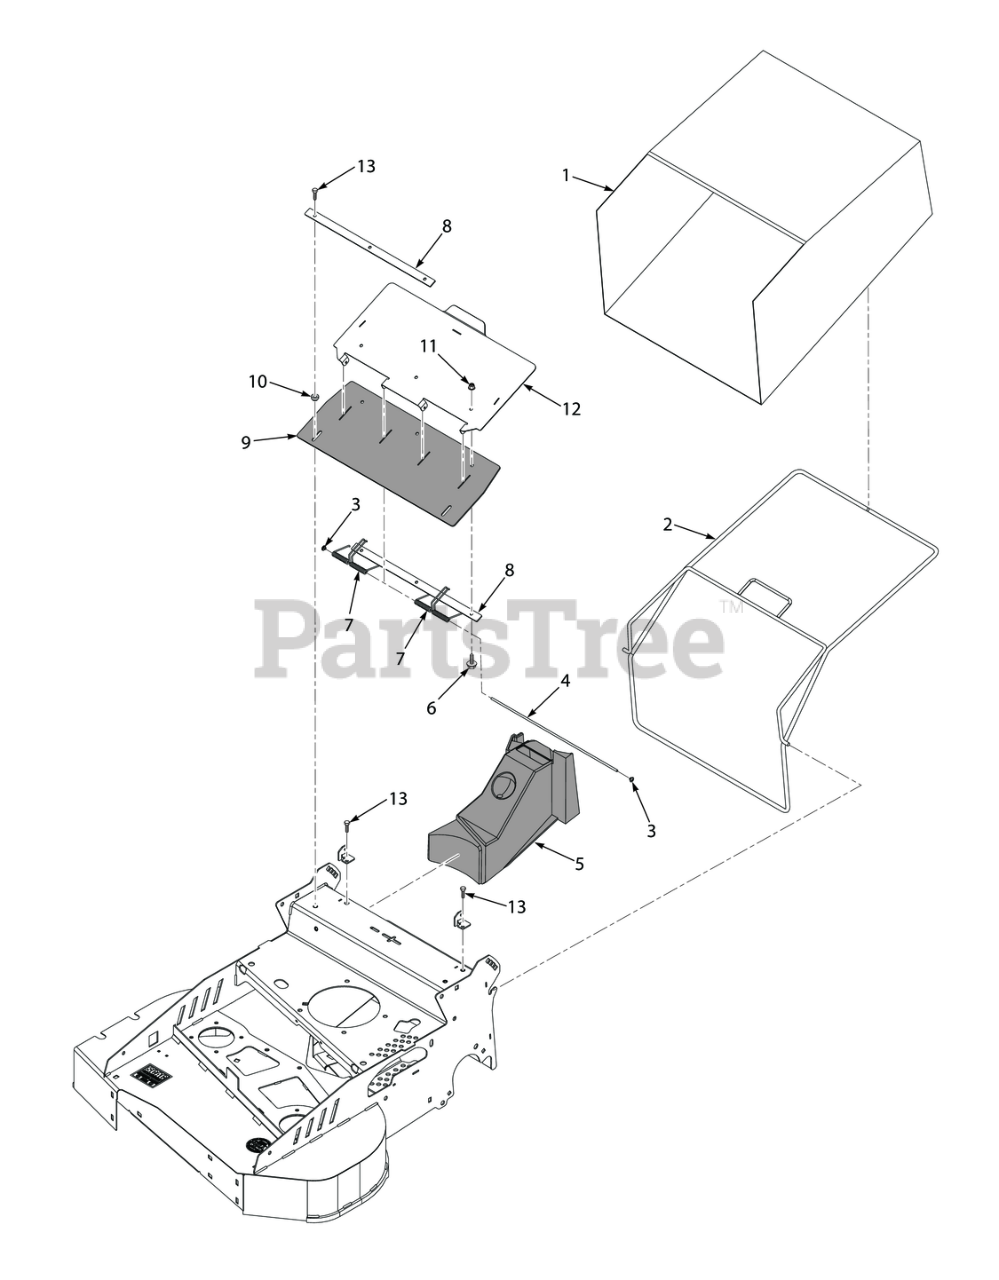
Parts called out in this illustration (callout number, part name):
1	Assembly, GC Bag (incl. #2)
2	Weldment, Bag Support
3	Nut, Push-on
4	Pin, Pivot
5	Blockoff Plug
6	BOLT, HEX HEAD, 1/4-20 X 3/4 GR.5
7	Spring, Rear Cover
8	Plate, Clamp
9	Gasket, Rear Cover
10	Pivot
11	Nut, Flanged Elastic Stop 1/4-20
12	Rear Cover Weldment
13	BOLT, HEX HEAD, 1/4-20 X 3/4 GR.5
